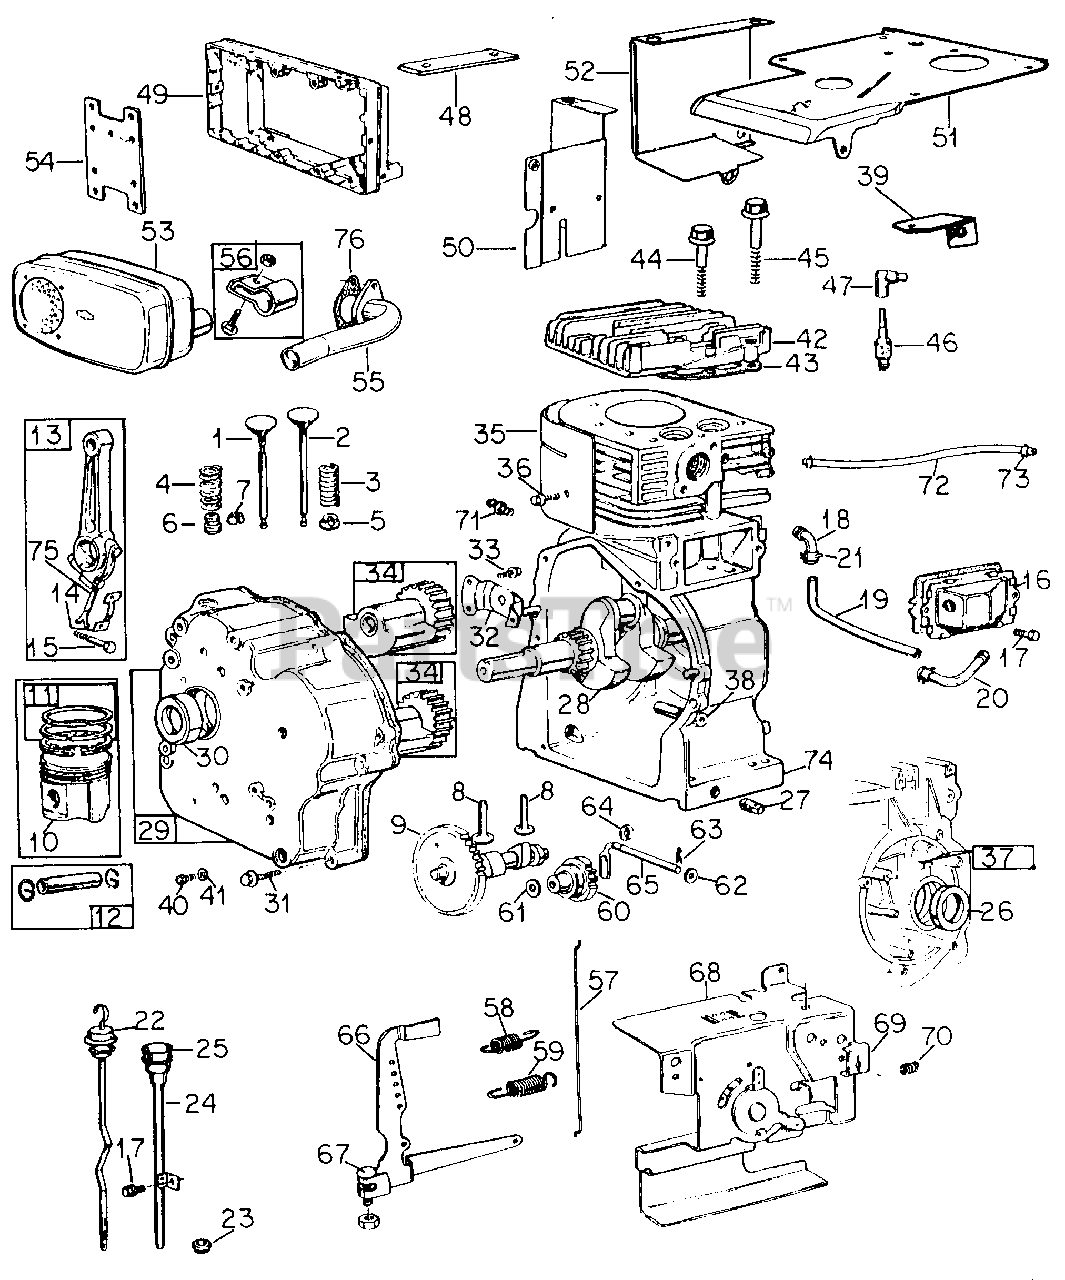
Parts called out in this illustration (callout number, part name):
1	Valve, Exhaust
2	Valve, Intake
3	Spring, Intake Valve
4	Spring, Exhaust Valve
5	Retainer, Intake Valve
6	Retainer, Exhaust Valve
7	Keeper, Exhaust Valve
8	Tappet, Valve
9	Camshaft and Gear
10	Piston Assy, Standard
11	Set, Piston Ring, Standard
12	Pin Assy, Piston
13	Rod Assy, Connecting
14	Lock, Connecting Rod Screw
15	Screw, Connecting Rod
16	Breather Assy
17	Screw, Breather & Oil Filler
18	Elbow, Breather
19	Tube, Breather
20	Elbow, Breather Tube
22	Dipper-Stick, Oil Fill Cap
23	Seal, Filler Tube, Lower
24	Tube Assy, Oil Filler & Dipper Stick
25	Seal, Oil Filler Tube, Upper
26	Seal, Oil
27	Plug, Oil Drain
29	Cover Assy, Crankcase
30	Seal, Oil
31	Screw, Cover Mounting
32	Retainer, Counterweight
33	Screw, Retainer
34	Counterweight & Bearing
35	Shield, Cylinder
36	Screw, Shield
37	Bushing, Governor Crank
38	Bushing, Plunger
39	Bracket, Support
40	Screw, No. 10 X 1/4 Znp H/Hd Mach
41	Washer, Flat Plug
42	Head, Cylinder
43	Gasket, Cylinder Head
44	Screw, Cylinder Head
45	Screw, Cylinder Head
46	Plug, Spark
47	Cover, Spark Plug Elbow
48	Strap, Bracket
49	Frame, Shroud
50	Cover Assy, Side
51	Hood, Upper Engine
52	Shroud, Exhaust Side
53	Muffler, Exhaust
54	Bracket, Muffler
55	Pipe Assy, Exhaust
56	Clamp Assy, Muffler
57	Link, Governor
58	Spring, Governor
59	Spring, Governor Idle
60	Gear, Governor
61	Washer, Thrust
62	Washer, Governor Crank
63	Pin, Hair Cotter
64	Retainer, E-Ring
65	Crank, Governor
66	Lever Assy, Governor
67	Bolt, Governor Lever
68	Plate, Governor Control
69	Clamp, Casing
70	Spring, Throttle Adj.
71	Connector, Fuel Pipe
72	Tube, Fuel Line
73	Clamp, Fuel Line
74	Crankcase - Not Serviced Separately
75	Dipper, Connecting Rod
76	Gasket, Exhaust Pipe
